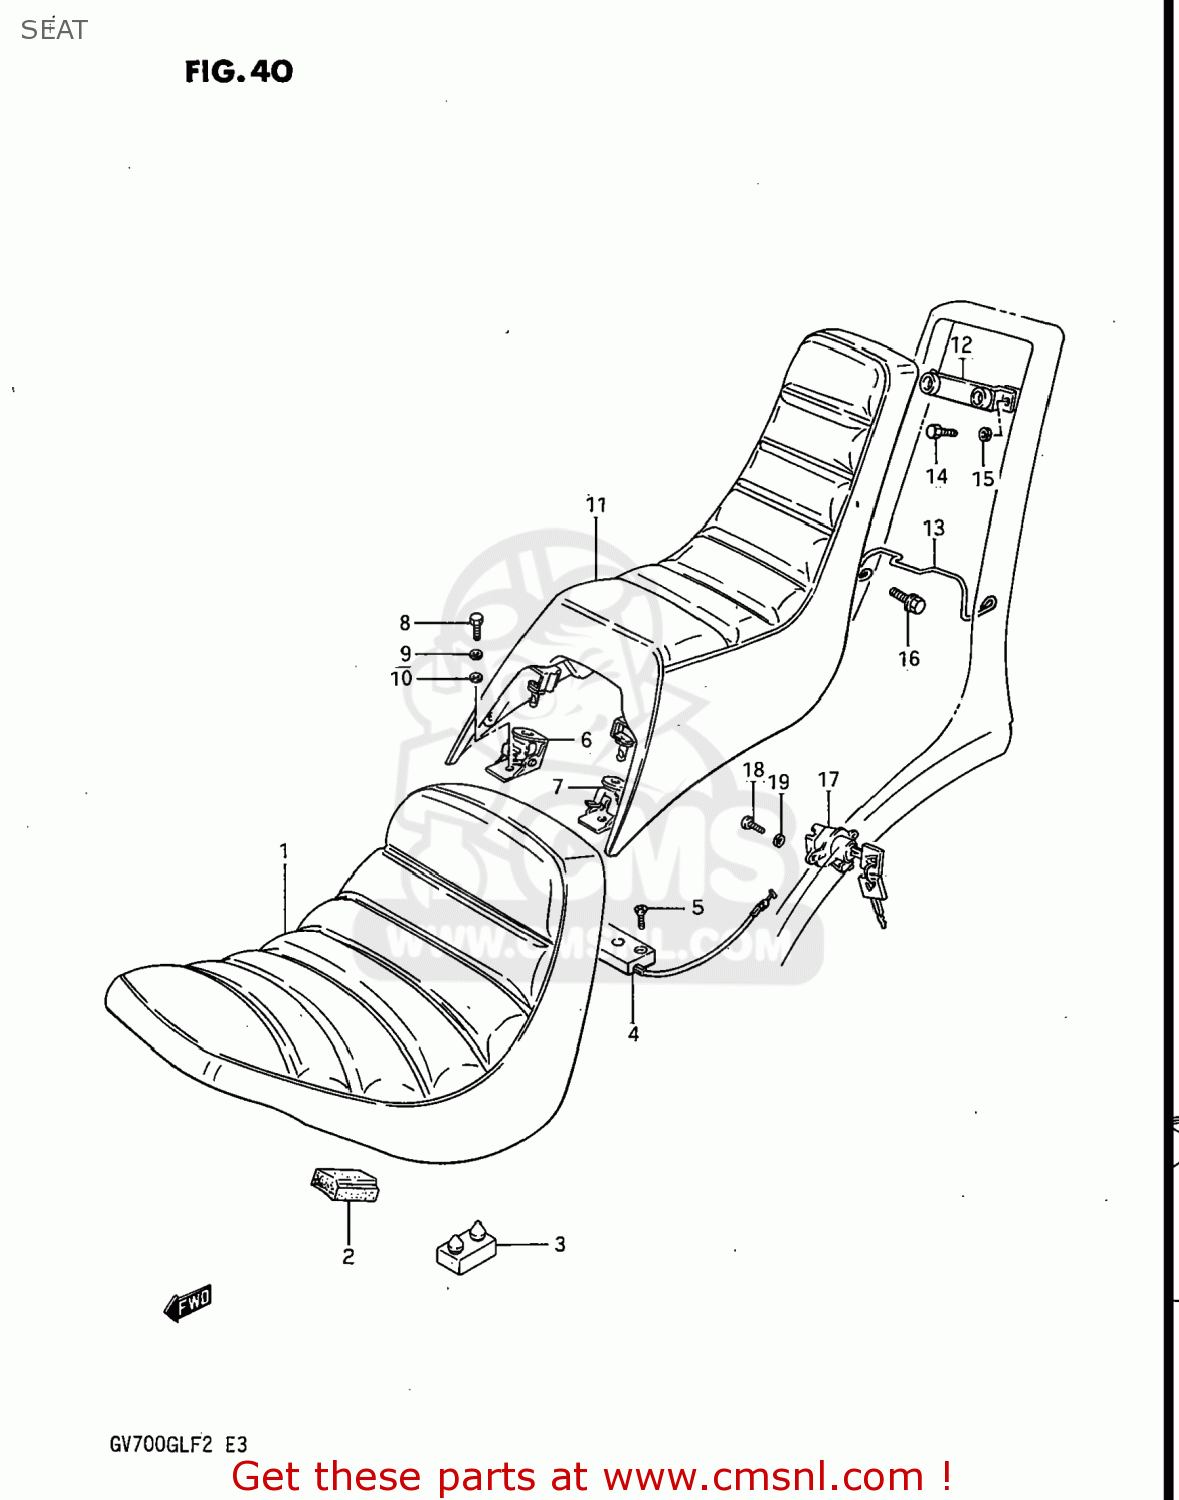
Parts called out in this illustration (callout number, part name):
1	SEAT ASSEMBLY
2	CUSHION,SEAT
3	CUSHION(40X23X12.7)
4	BRACKET,SEAT SUPPORT
5	SCREW
8	BOLT
9	WASHER,LOCK
10	WASHER, LOWER
11	SEAT,PILLION
12	PLATE,SEAT SUPPORT PILLION
13	ROD,SEAT SUPPORT PILLION
14	BOLT, UPPER
15	LOCK WASHER
16	BOLT
17	LOCK SET,SEAT
18	SCREW
19	WASHER
